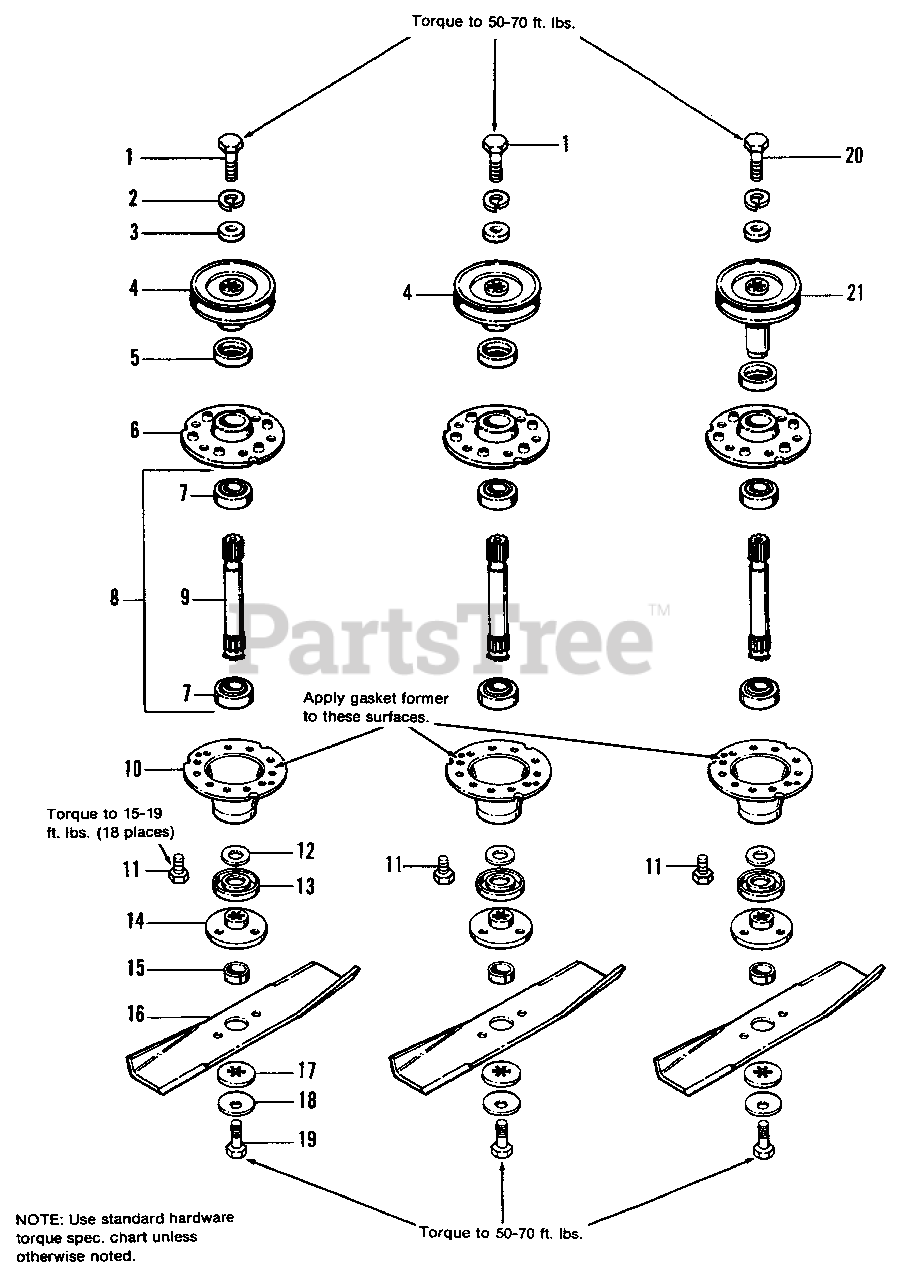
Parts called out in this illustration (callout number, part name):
1	CAPSCREW, Hex, 7/16-14 x 1-3/4
2	LOCKWASHER, 7/16
3	WASHER, Plain, 29/64 x 1-1/4 x 1/4
4	PULLEY ASSY.
5	SHIELD, Bearing Upper, Arbor
6	HOUSING TOP
8	SHAFT & BEARING ASSY. (Incl. Ref. Nos. 7, 9 & 15)
9	SHAFT, Arbor (Incl. Ref. No. 15)
10	HOUSING, Bottom
11	SCREW, Hex, Taptite, 5/16-18 x 3/4
12	WASHER, Shim
13	SHIELD, Grass
14	BLADE, Adaptor
15	COLLAR, Mower Arbor
16	BLADE, 42" Mower 1690708 only)
16	BLADE, 48" Mower (1690709 only)
17	WASHER, Spline
18	WASHER, Spring
19	CAPSCREW, Hex, 7/16-14 x 1
20	CAPSCREW, Hex, 7/16-14 x 3-1/2
21	PULLEY ASSY.
